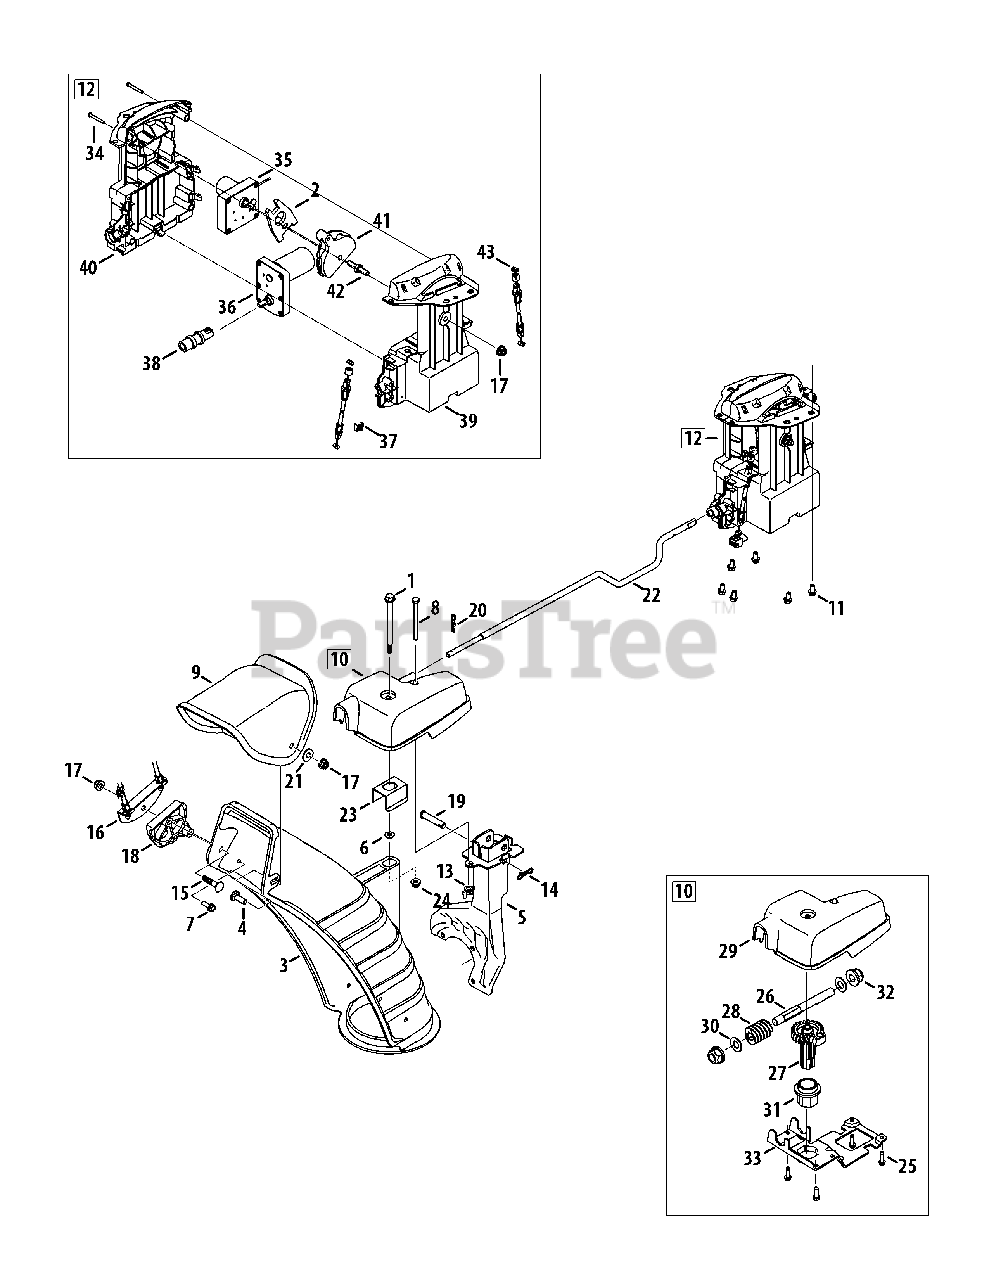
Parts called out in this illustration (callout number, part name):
1	Flange Shoulder Screw
2	Adpt., Pitch, Chute
3	Lower Chute
4	Carriage Bolt, 5/16-18 x 1.0
5	Chute Support Bracket
6	Flat Washer, .25 x .630 x .0515
7	Hi-Lo Screw, 1/4-15 x .75
8	Hex Screw, 1/4-20 x 3.00
9	Upper Chute
10	Electric Chute Gearbox Assembly
11	Hi-Lo Screw, 1/4-15 x 0.5
12	Electric Chute Control Assembly
13	Wing Nut, 1/4-20
14	Bow Tie Cotter Pin
15	Carriage Bolt, 5/16-18 x 1.50
16	Cable Bracket
17	Flange Lock Nut, 5/16-18
18	Chute Tilt Cable Guide
19	Clevis Pin
20	Cotter Pin
21	Flat Washer, .349 x .879 x .063
22	Chute Rod
23	Chute Bracket
24	Flange Lock Nut, 1/4-20
25	Screw, #12-16 x .75
26	Shaft, Worm Drive
27	Gear, Helical
28	Worm, 2-Start Nylon
29	Cover, Gear, Chute Control
30	Wash., Flat, .510 x 1.00 x .060
31	Bearing, Flange, 1.00 ID
32	Bearing, Flange, .50 ID
33	Brkt., Gear, Chute Rotation
34	Scr., AB, #10-16 x 1.25
35	Motor, Pitch, Chute
36	Motor, Rotate, Chute
37	Clip, Cable
38	Coupler, Electric Chute
39	Hsg., LH, 4-Way, Chute Control
40	Hsg., RH, 4-Way, Chute Control
41	Gde., Cbl., Chute Tilt
42	Scr., Hex, 5/16-18 x .75
43	Cbl., Snow, 4-Way, Tall Chute
